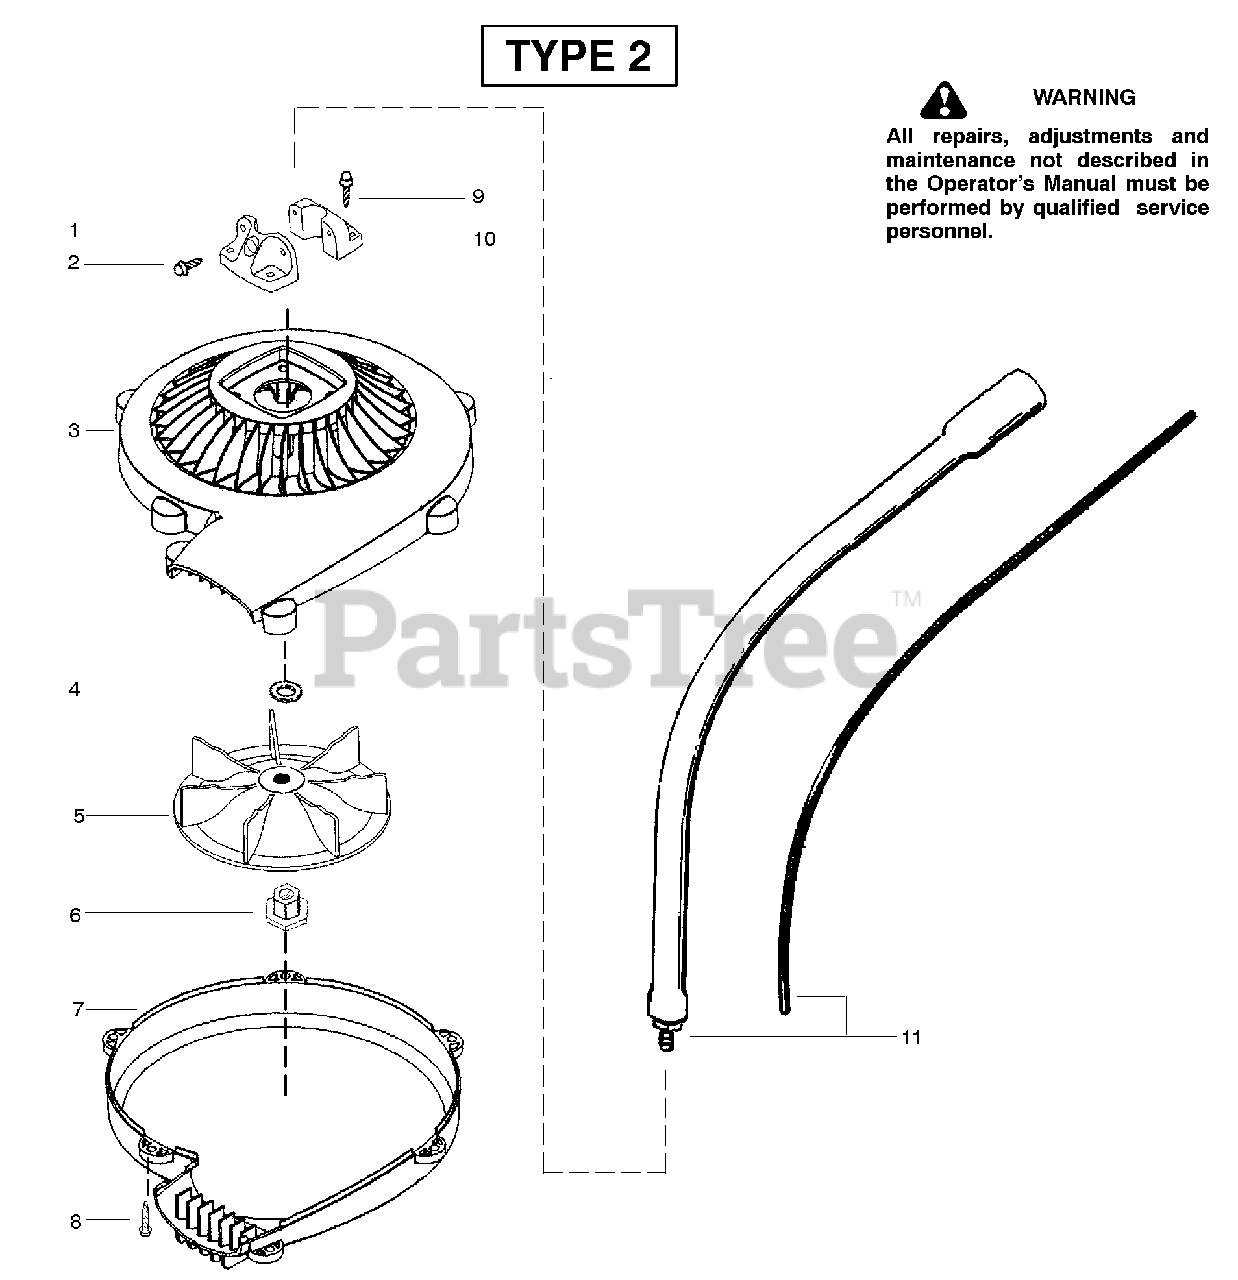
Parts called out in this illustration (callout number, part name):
1	Clamp-Right
3	Hsg.-Blower (upper)
5	Impeller
6	Arbor-Impeller
7	Hsg.-Blower (lower)
10	Clamp-Left
11	Kit-Lower Driveshaft
11	Hanger-Attachment
11	Decal-Warning
